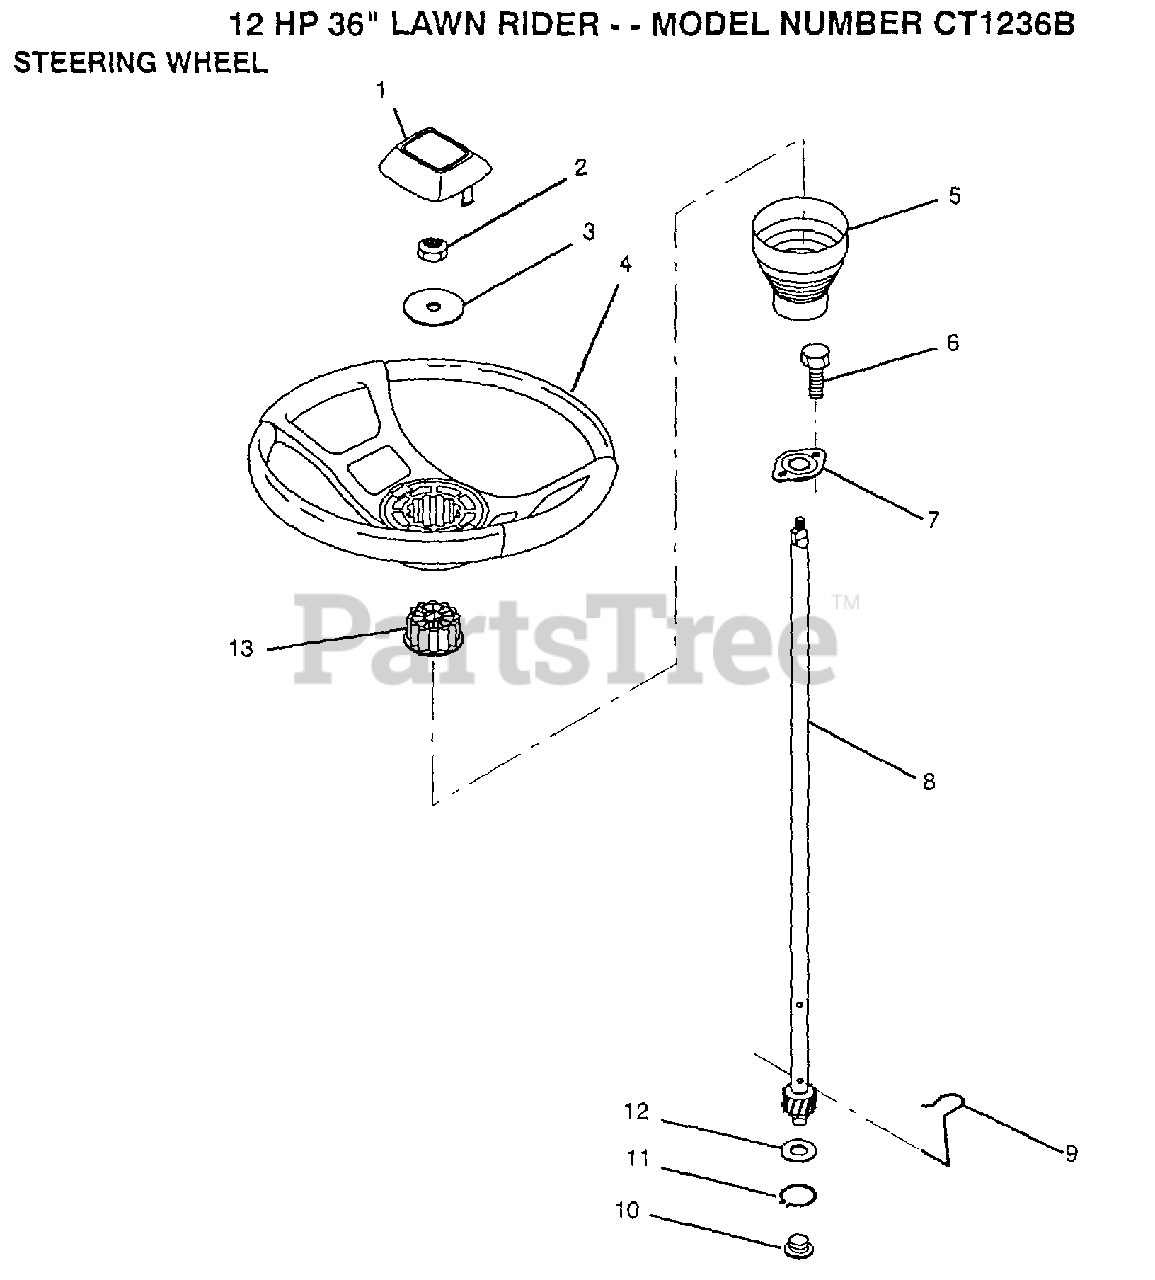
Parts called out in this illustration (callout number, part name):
1	INSERT-WHEEL LT
2	GRIPCO NUT
3	WASHER T
5	SLEEVE STEERING
9	STEERING CLIP
10	BUSHING STEER LWR
11	RING
12	WASHER LT
13	ADAPTER-WHEEL LT
